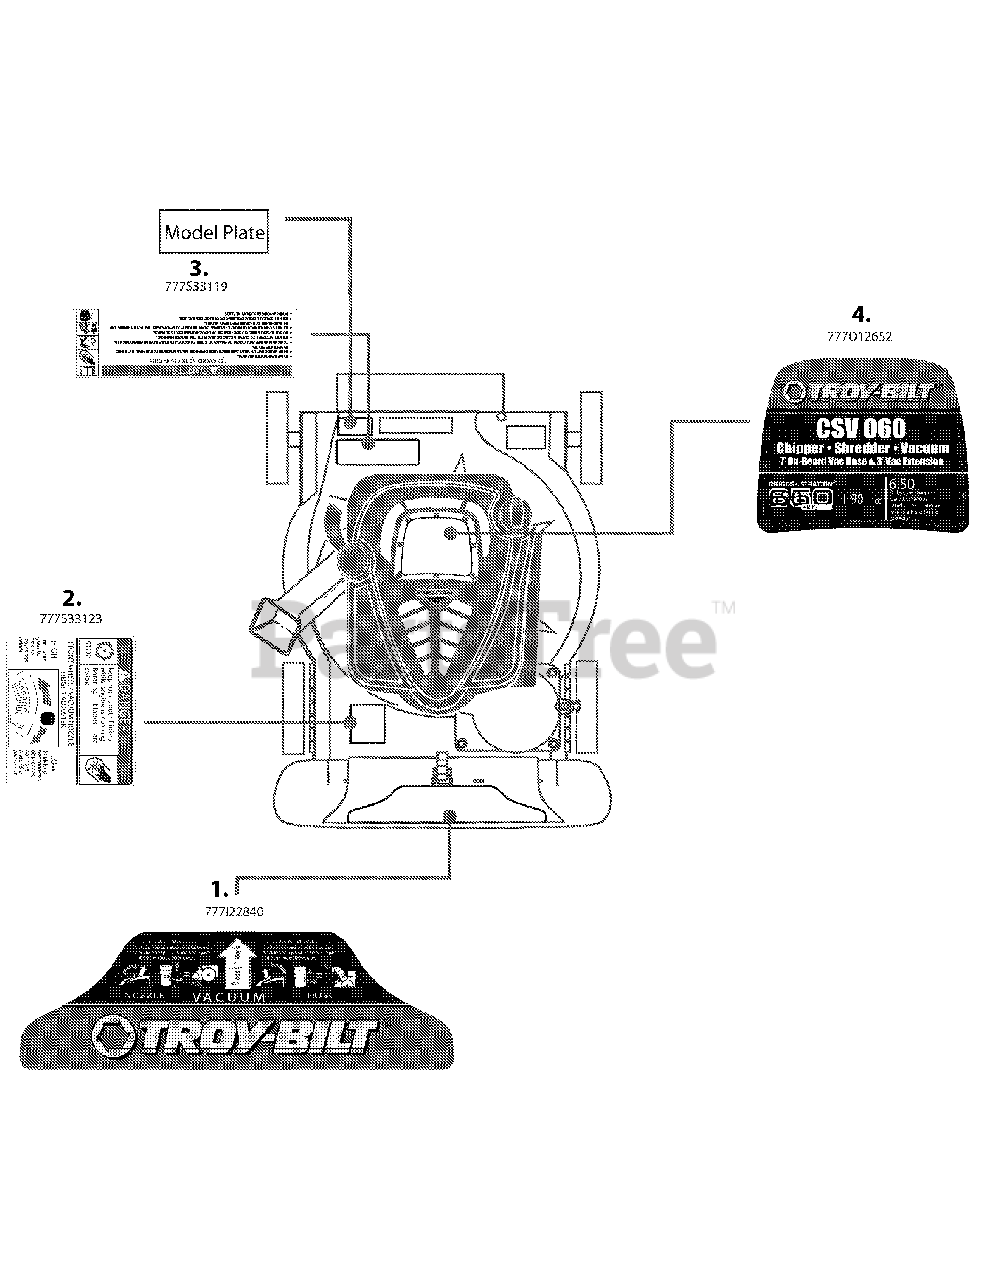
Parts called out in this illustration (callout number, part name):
1	LABEL-CSV NOZZLE TROY
2	LABEL-CSV BLADES DANGER
3	LABEL-CSV DANGER
4	LABEL-CSV TROY
